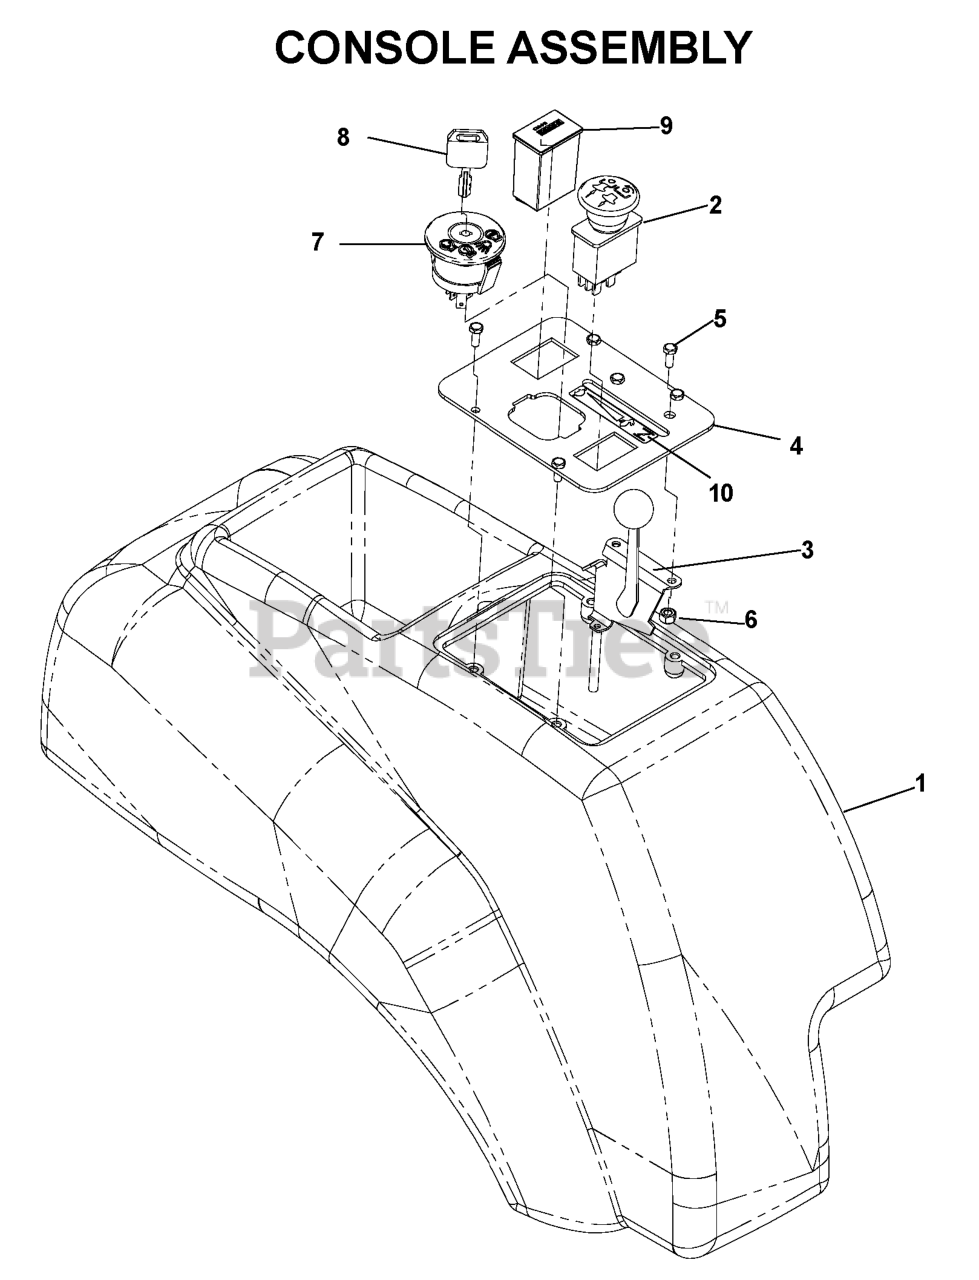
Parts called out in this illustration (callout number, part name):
1	FENDER CONSOLE
2	RP.SWITCH, BLADE
3	THROTTLE CABLE DETENT
4	CONTROL CONSOLE-BLACK
5	HCS #10-24 X 1/2
6	NUT 10-24 NYLOC
7	RP IGNITION SWITCH
8	KEY
9	HOUR METER
10	DECAL-THROTTLE
